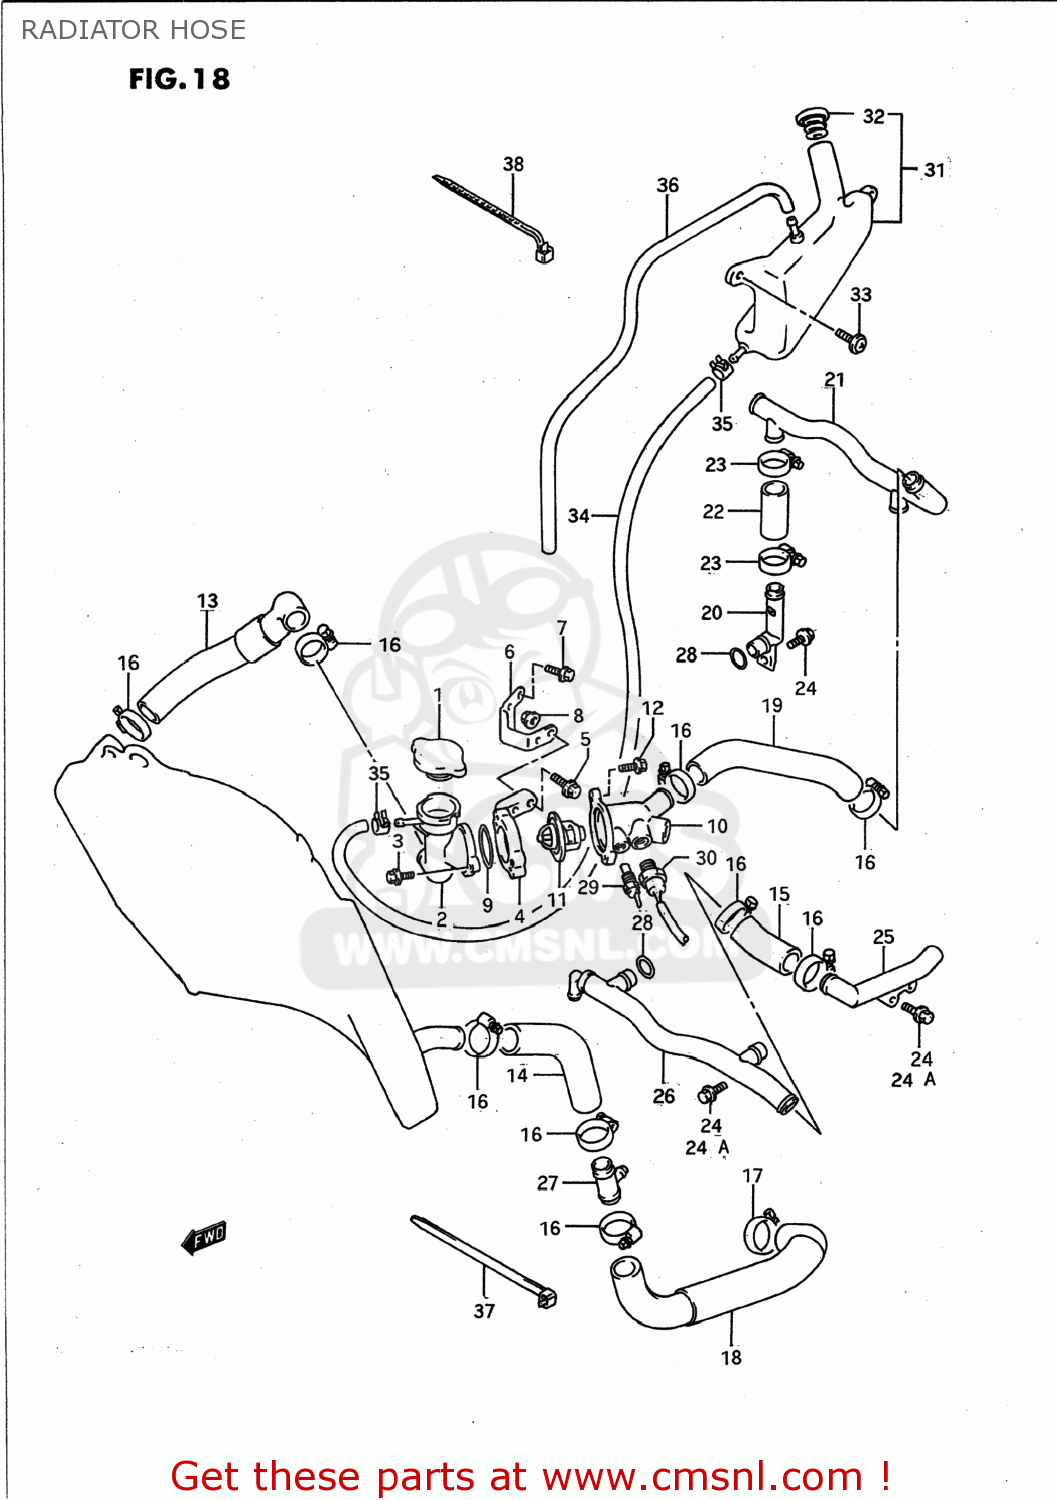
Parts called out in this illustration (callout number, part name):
1	CAP,RADIATOR
2	CONDUCTION,RADIATOR
3	BOLT
4	BRACKET,CONDUCTION
5	BOLT
6	BRACKET,CONDUCTION BRAKE
7	BOLT
8	NUT
9	O RING(D:2.4,ID:43.2)
10	CONNECTOR,THERMOSTAT INLET
11	THERMOSTAT,WATER
12	BOLT
13	HOSE,WATER
14	HOSE,RADIATOR OUTLET
15	HOSE,WATER
16	CLAMP
17	CLAMP
18	HOSE,WATER PUMP INLET
19	HOSE,HEAD OUTLET
20	PIPE,HEAD OUTLET
21	PIPE COMP,HEAD OUTLET
22	HOSE,WATER
23	CLAMP
24	BOLT
24A	BOLT(6X36)
25	PIPE,CYLINDER SIDE
26	PIPE,CYLINDER INLET
27	UNION,HOSE JOINT
28	O RING(D:3.2,ID:17.8)
29	GAUGE ASSY,WATER TEMP
30	SWITCH COMP,RADIATOR FAN
31	TANK ASSY,RESERVOIR
32	CAP,RESERVOIR TANK
33	SCREW(6X20)
34	HOSE,RESERVOIR TANK INLET
35	CLIP
36	HOSE,RESERVOIR TANK OVERFLOW
37	CLAMP
38	CLAMP(L:165)
